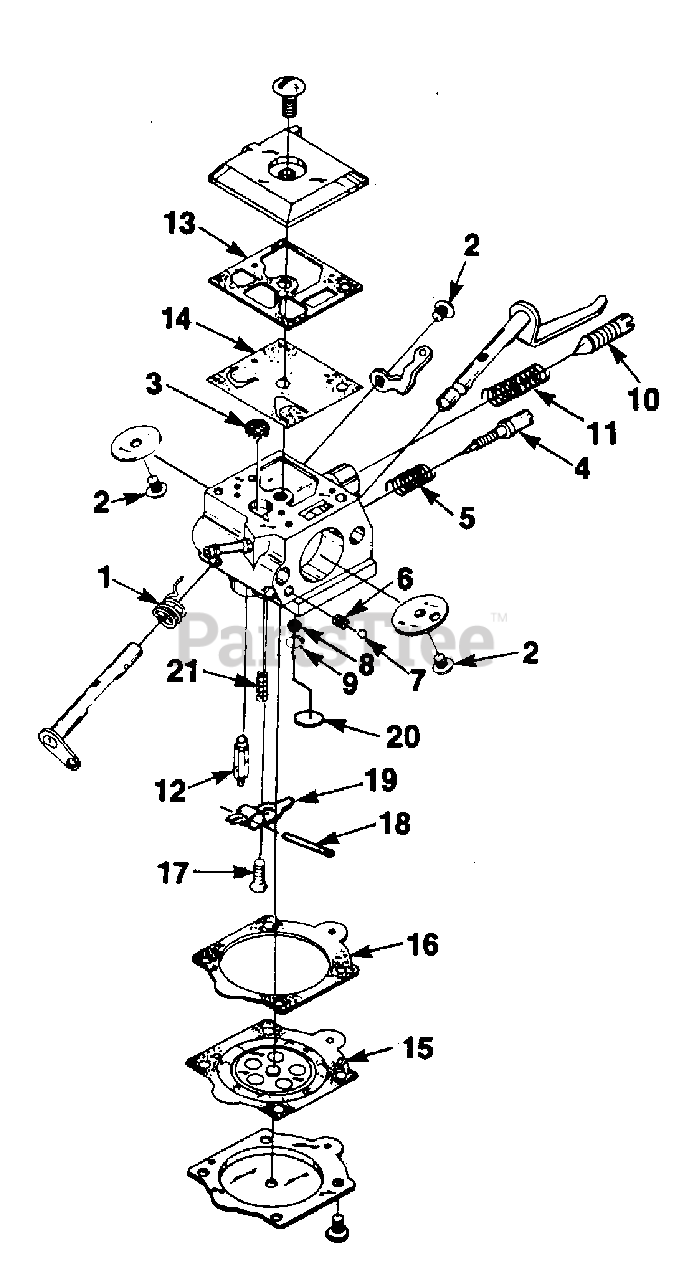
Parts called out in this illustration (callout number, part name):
1	Repair Kit
2	Repair Kit
3	Repair Kit
4	Repair Kit
5	Repair Kit
6	Repair Kit
7	Repair Kit
8	Repair Kit
9	Repair Kit
10	Repair Kit
11	Repair Kit
12	Repair Kit
13	Repair Kit
14	Repair Kit
15	Repair Kit
16	Repair Kit
17	Repair Kit
18	Repair Kit
19	Repair Kit
20	Repair Kit
21	Repair Kit
